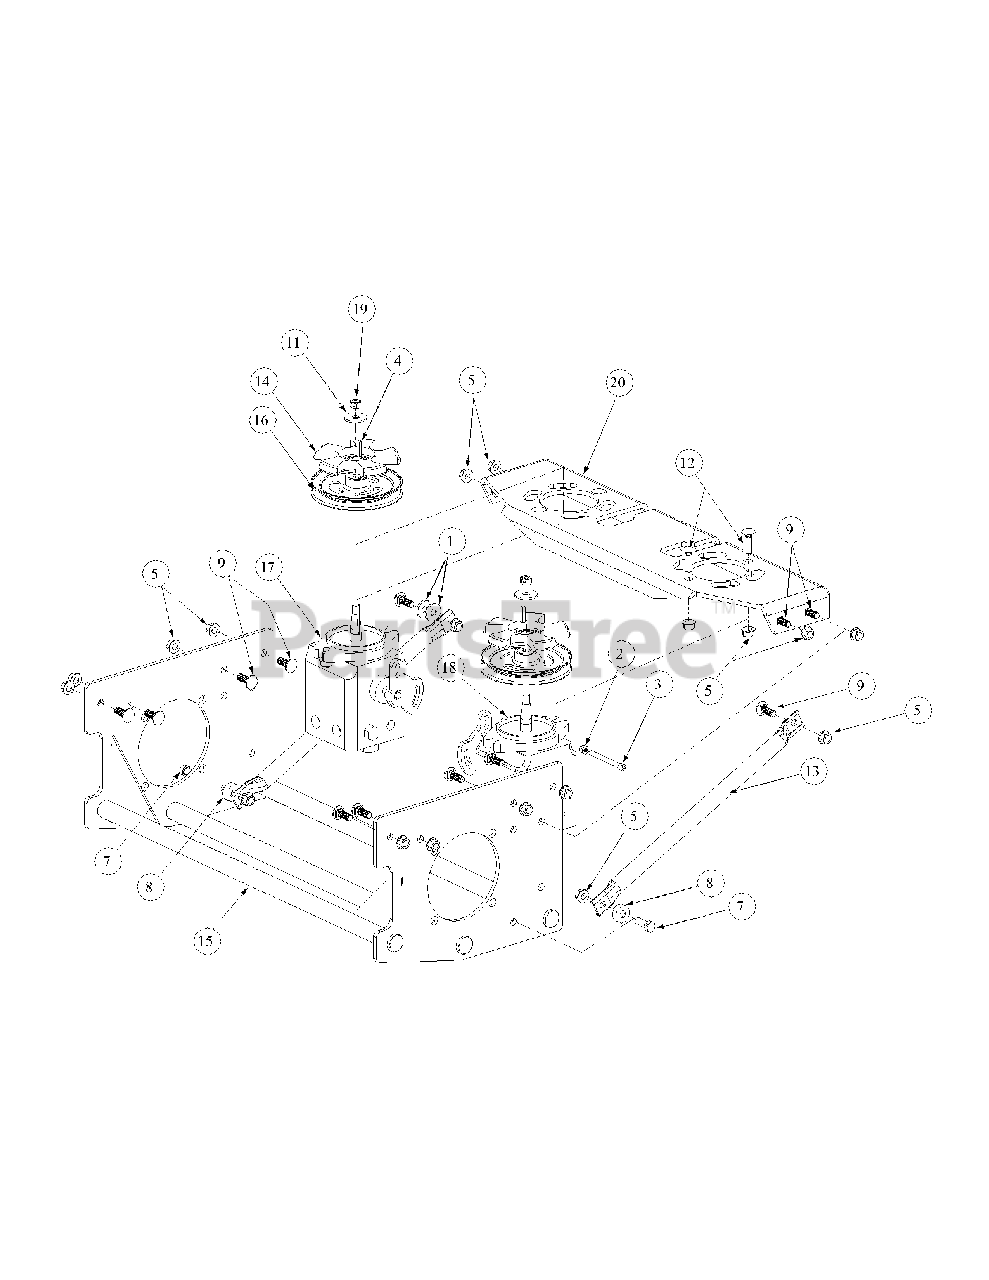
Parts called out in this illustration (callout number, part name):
1	Washer lock 3/8 zinc
2	Lock Nut, Nylon Insert, 1/4-20
3	Socket Head Cap Screw, 1/4-20 x 2-1/2
4	Key, 3/16" x 7/8"
5	Flange Lock Hex Nut, 3/8-16
7	Hex Cap Screw, 2/8 -16 x 1.25
8	Spacer, .406 ID x 1.00 OD x .38
9	Carriage Bolt, 3/8-16 x 1
11	Flat Washer, .411 x 1.25 x .100
12	Carriage Screw, 3/8-16 x 1.25
14	Hydro Pulley Fan
15	Hydro Motor Frame Assembly
16	Hydro Pulley Pump
17	Hydro Pump, LH
18	Hydro Pump, RH
19	Hex Nut, 3/8-24
20	Hydro Pump Mounting Weldment
